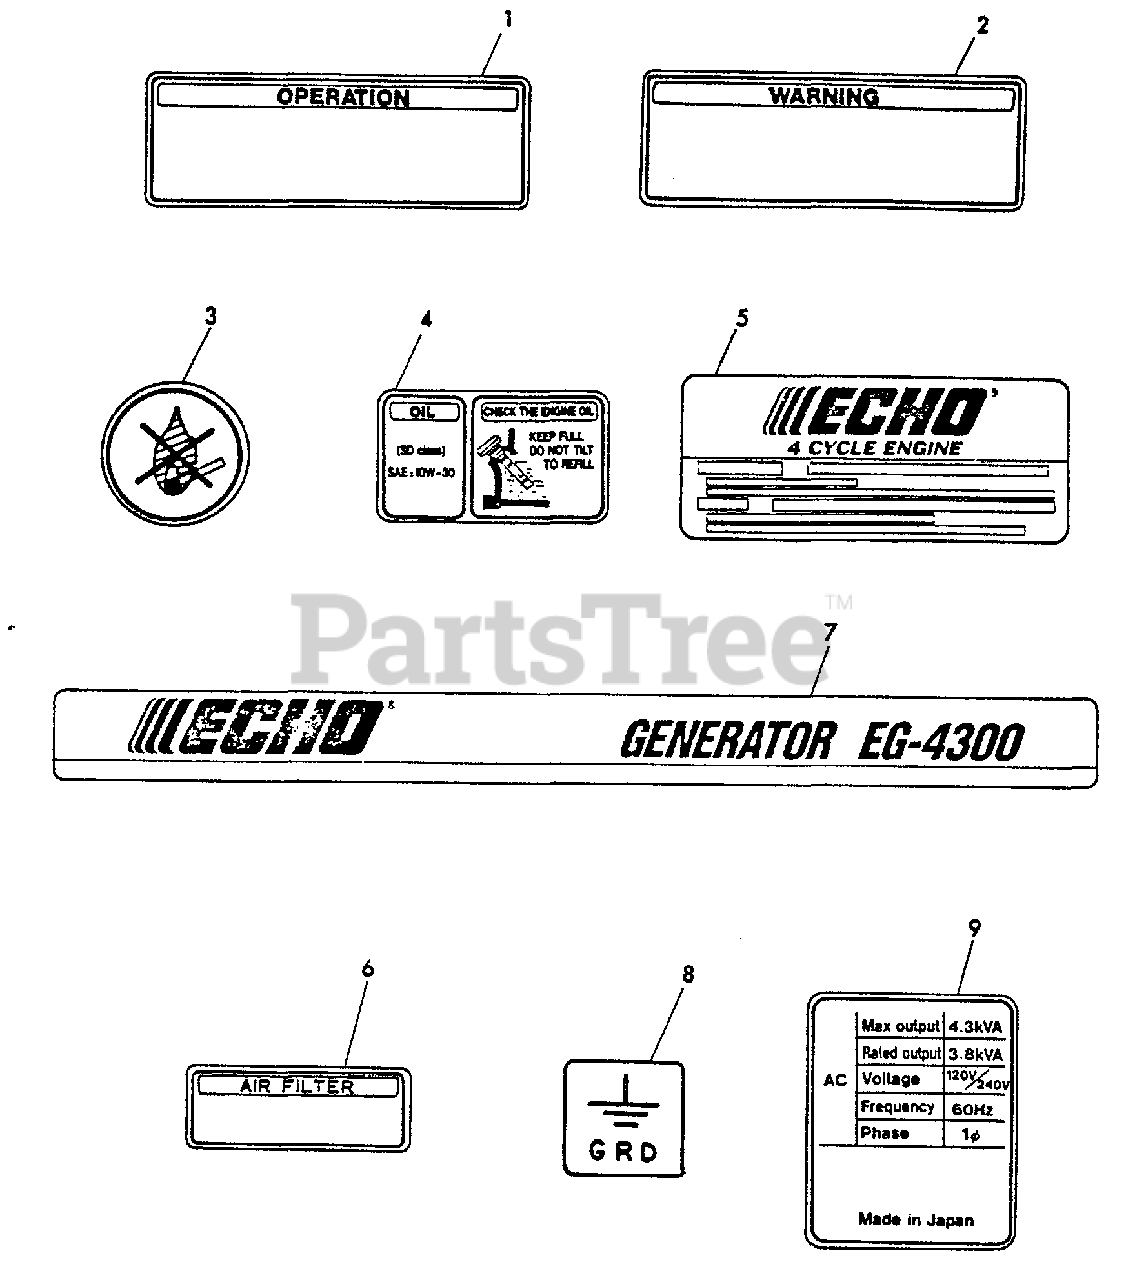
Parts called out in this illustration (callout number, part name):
1	LABEL - OPERATION
2	LABEL - WARNING
3	LABEL - NON FIRE
4	LABEL - OIL
5	LABEL - ECHO
6	LABEL - AIR CLEANER
7	LABEL - MODEL EG4300
8	LABEL - GROUND
9	LABEL - GENERATOR
